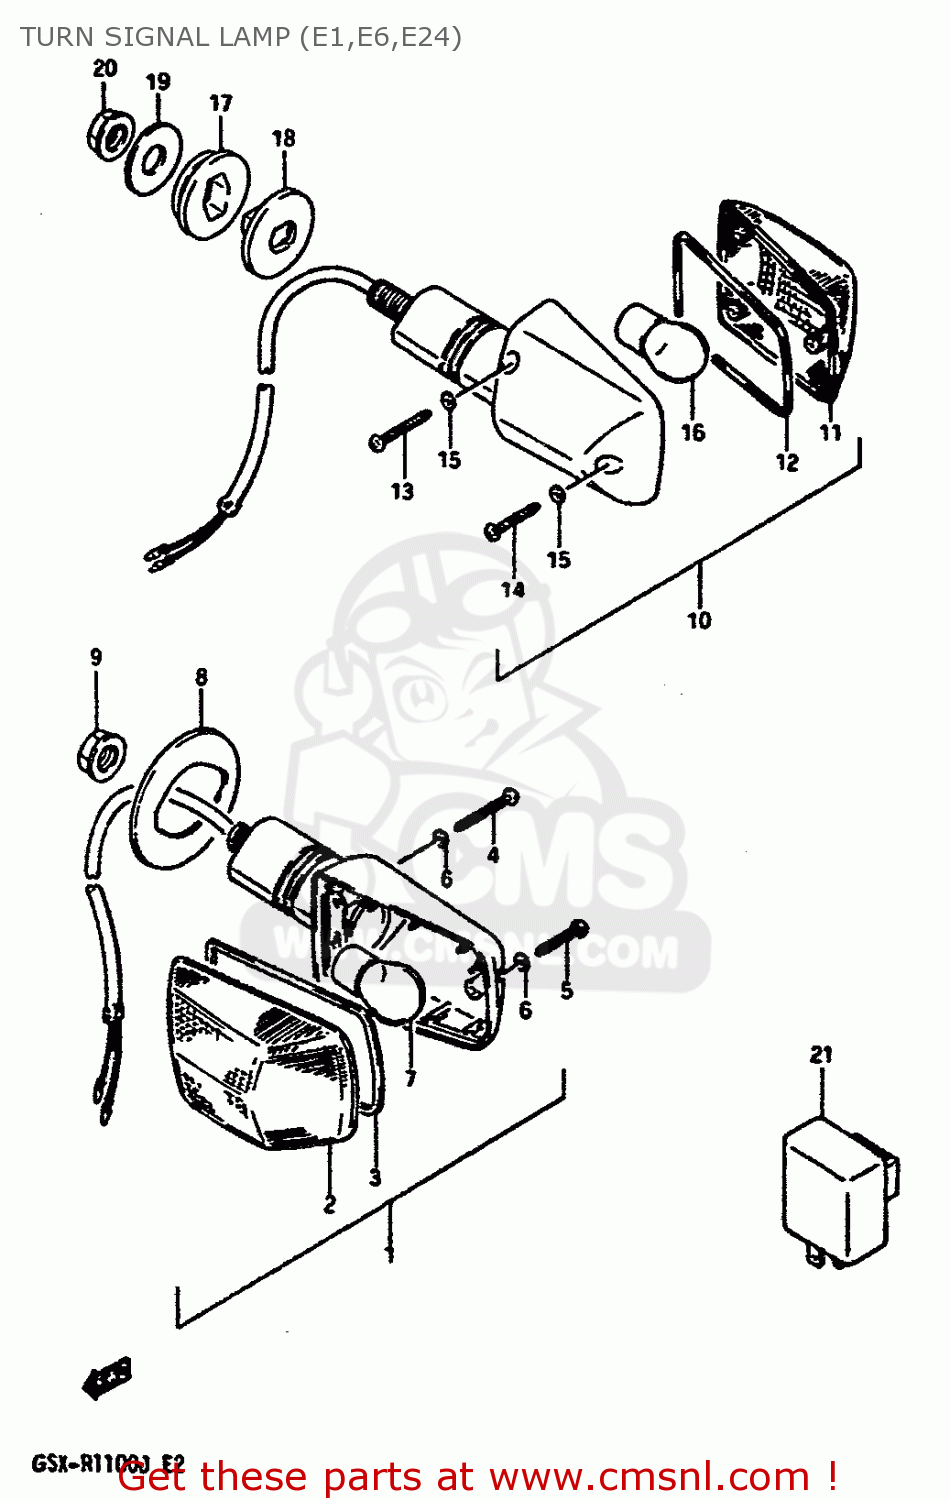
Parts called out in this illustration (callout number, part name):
1	LAMP ASSY,FRONT TURN SIGNAL
2	LENS,TURNSIGNAL
3	GASKET (NAS)
4	SCREW(3X30)
5	SCREW
6	GASKET (NAS)
7	BULB(12V23W,STANLEY,A4577A)
8	GROMMET
9	NUT
10	LAMP ASSY,REAR TURN SIGNAL
11	LENS,TURNSIGNAL
12	GASKET (NAS)
13	SCREW(3X30)
14	SCREW
15	GASKET (NAS)
16	BULB(12V23W,STANLEY,A4577A)
17	CUSHION
18	SPACER
19	WASHER (10.2X27X1.6)
20	NUT
21	RELAY ASSEMBLY,TURN SIGNAL
